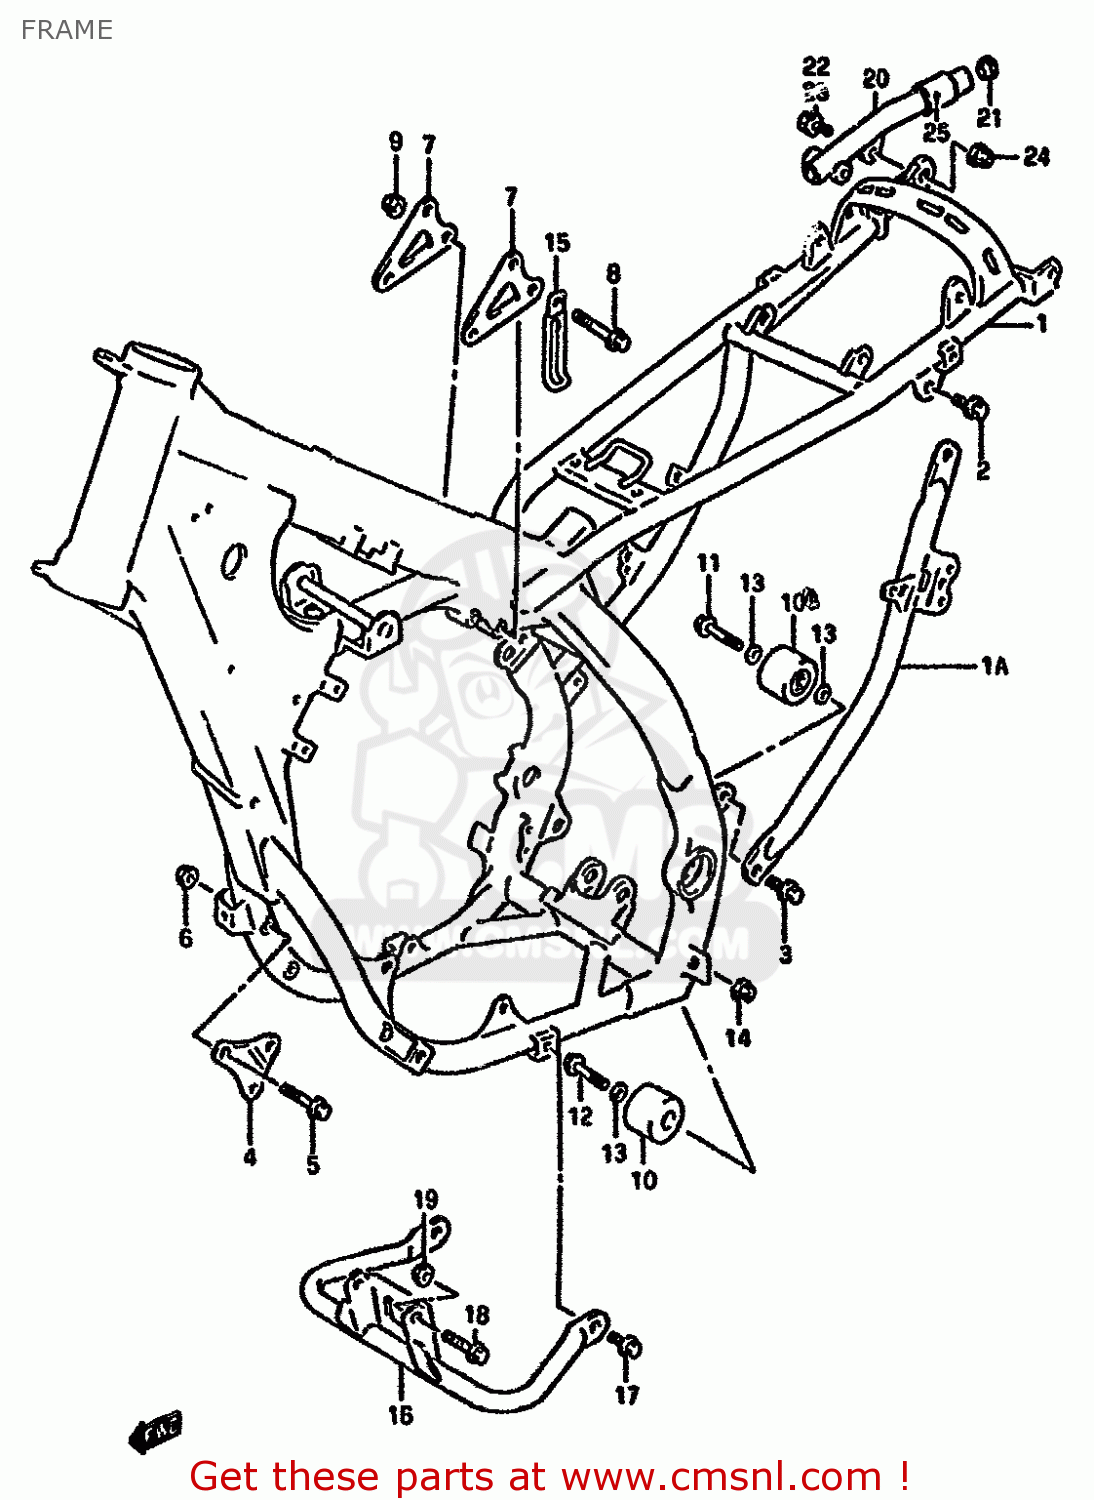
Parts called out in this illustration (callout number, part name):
1	FRAME SET (CHARCOAL)
1A	TUBE,FRAME SIDE (CHARCOAL)
2	BOLT
3	BOLT
4	PLATE,ENG MTG FR
5	BOLT
6	NUT
7	PLATE,ENG MTG UPR
8	BOLT(8X41)
9	NUT
10	ROLLER,CHAIN
11	BOLT(8X41)
12	BOLT(8X45)
13	WASHER
14	NUT
15	CLAMP
16	PROTECTOR,ENGINE
17	BOLT 8X55
18	BOLT(8X14)
19	NUT
20	GRIP,REAR RH
21	PLUG(OD:17)
22	BOLT
23	BOLT
24	NUT
25	BUSHING (D10)
